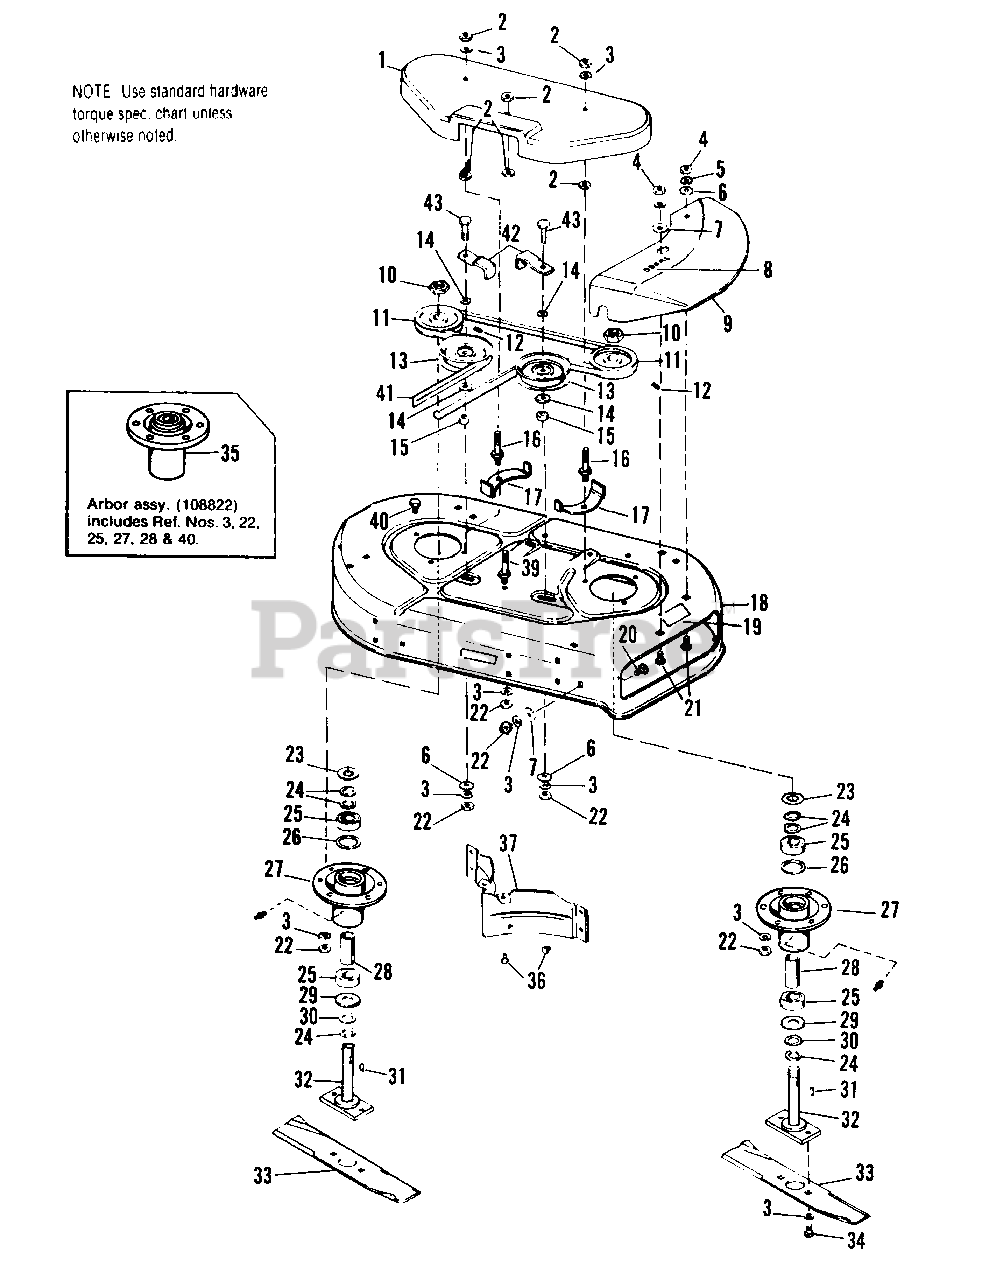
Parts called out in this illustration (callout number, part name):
1	COVER, Housing
2	LOCKNUT, Hex, 3/8-16
3	LOCKWASHER, 3/8
4	NUT, Hex, Full, 5/16-18
5	LOCKWASHER, 5/16
6	WASHER, Plain, 5/16
7	WASHER
8	DECAL, Safety
9	DEFLECTOR
10	LOCKNUT, Hex, 3/4-16
12	SETSCREW, 5/16-18 x 3/8
13	PULLEY, Idler
14	WASHER, Plain, 3/8
17	GUIDE, Belt
18	HOUSING, Mower, 28"
19	FILM, Safety
20	BOLT, Carriage, 3/8-16 x 3/4
21	BOLT, Carriage, 5/16-18 x 3/4
22	NUT, Hex, Full, 3/8-16
26	RING, Backing
27	TUBE ASSY., Arbor
31	KEY
32	ARBOR ASSY.
34	CAPSCREW, Hex Hd., 3/8-16 x 5/8
35	ARBOR ASSY., W/Bearings
36	SCREW, Hex, Self Tapping, 1/4-20 x 3/8
38	DECAL, Simplicity
40	CAPSCREW, Hex Hd., 3/8-16 x 3/4
41	V-BELT, Drive
42	GUIDE, Belt
43	CAPSCREW, Hex Hd., 3/8-16 x 1-3/4
